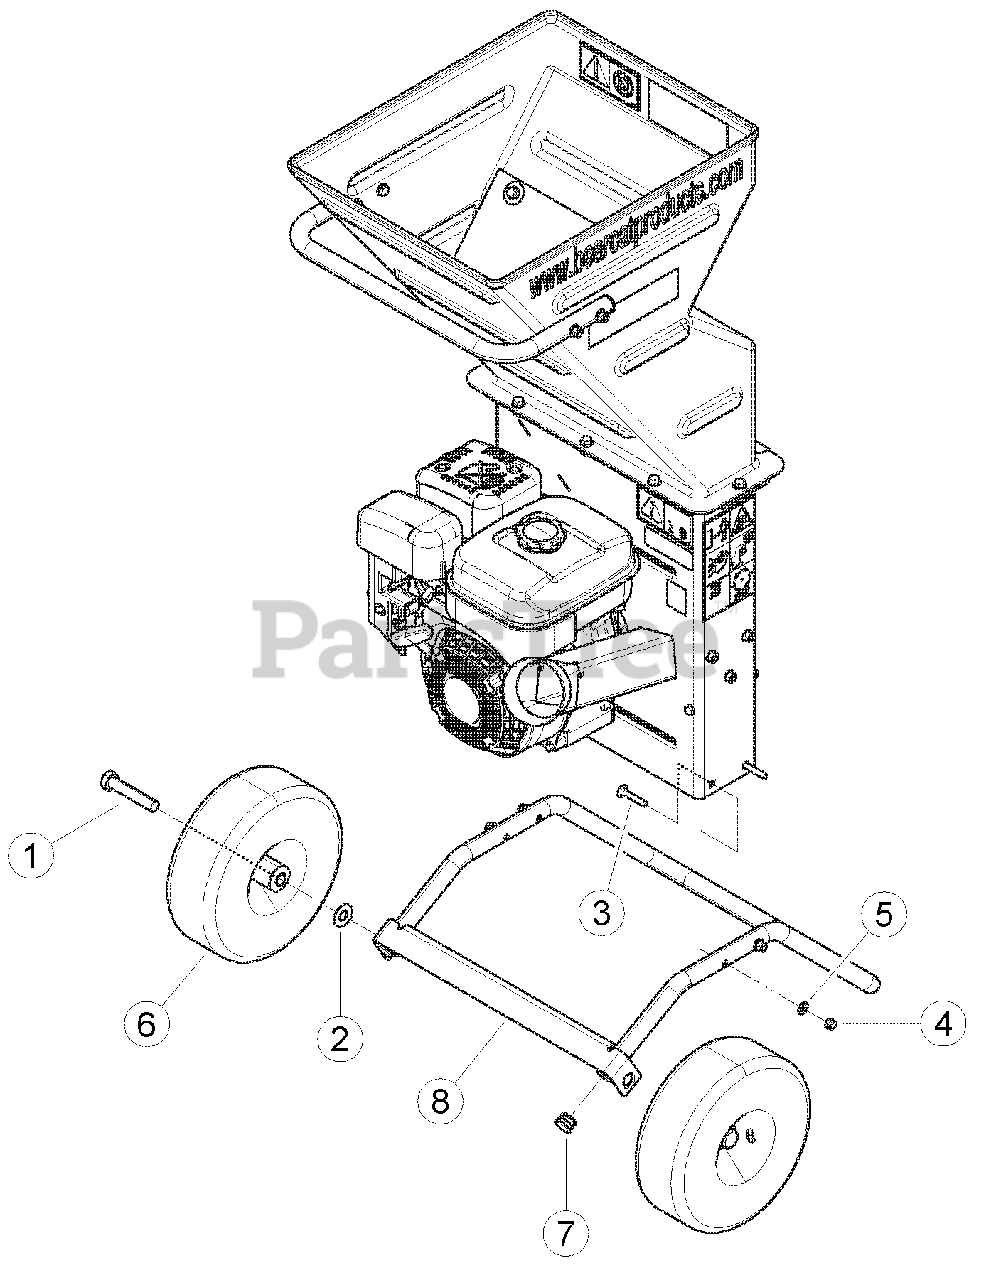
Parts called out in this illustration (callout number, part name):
1	BOLT, 5/8 X 3-1/4 HEX HD GR5 ZP
2	WASHER, 5/8 SAE FLAT ZP
3	BOLT, 5/16 X 1-3/4 CRG GR5 ZP
4	NUT, 5/16 NE NYLOCK ZP
5	WASHER, 5/16 SAE FLAT ZP
6	WHEEL ASSY, 410/350-4
7	PLUG, 1" ROUND RIBBED
8	WELDMENT, STAND
